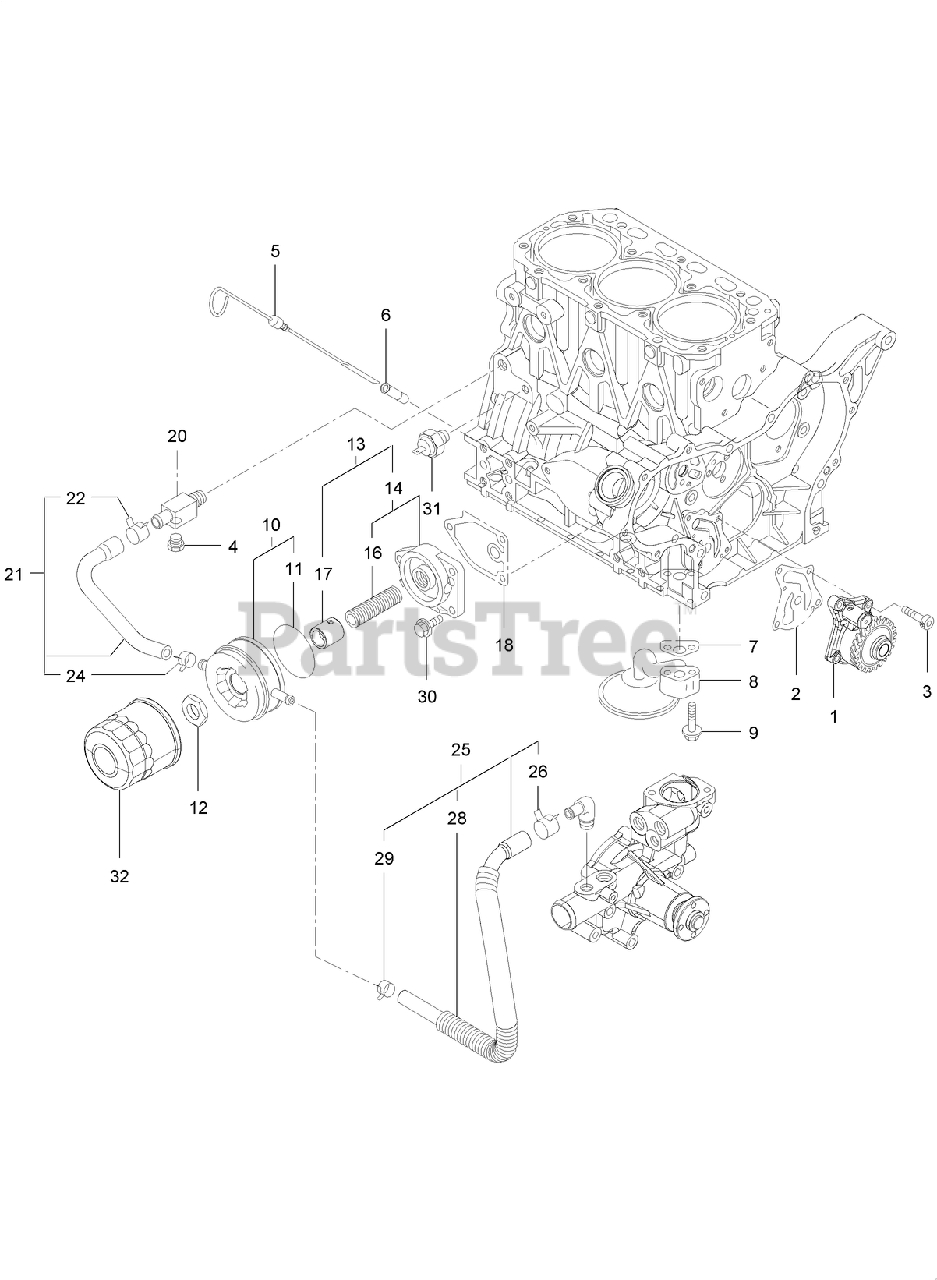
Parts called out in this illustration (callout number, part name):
1	OIL PUMP ASM
2	GASKET
4	PLUG-DRAIN
5	DIPSTICK
6	GUIDE-DIPSTICK
7	GASKET
8	PIPE ASM-OIL INLET
10	COOLER ASM-OIL
11	PACKING-OIL COOLER
13	BRACKET ASM-LO FILT
14	BRACKET ASM
17	COLLAR-OIL COOLER
18	GASKET
21	PIPE ASM
24	CLAMP-HOSE
25	PIPE ASM
29	CLAMP-HOSE
31	SWITCH-OIL
32	FILTER-ENGINE
